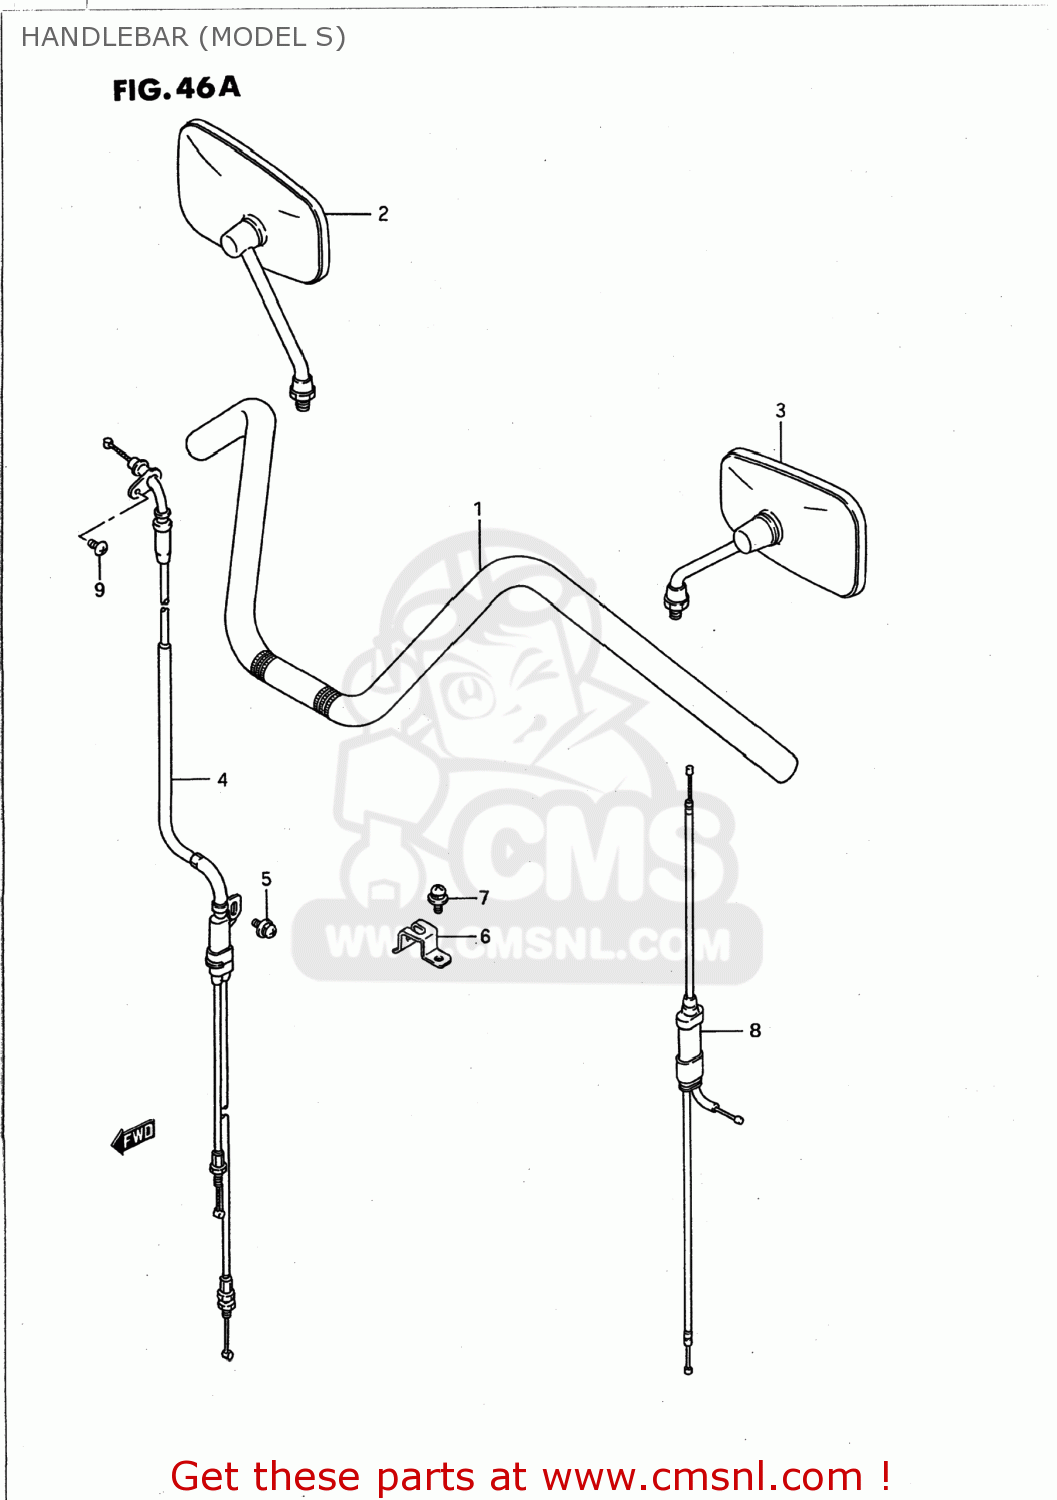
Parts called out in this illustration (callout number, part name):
1	HANDLEBAR
2	MIRROR ASSEMBLY,REAR VIEW
3	MIRROR ASSEMBLY,REAR VIEW
4	CABLE ASSY,THROTTLE
5	SCREW
6	CLAMP,THROTTLE CABLE CONNECTOR
7	SCREW
8	CABLE ASSEMBLY,STARTER
9	SCREW
